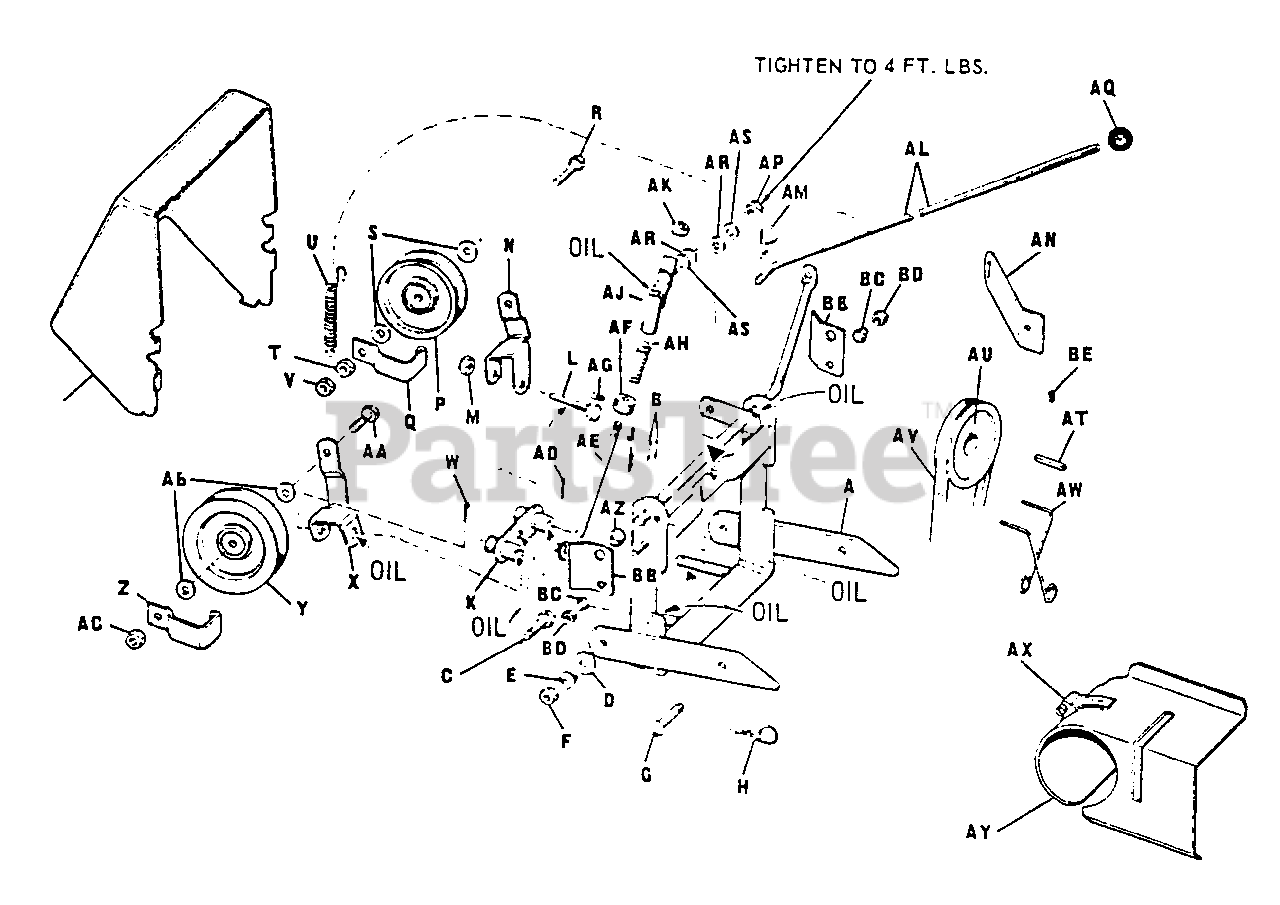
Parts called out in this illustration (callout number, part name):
A	Hitch Assembly
B	Cotter Pin, 1/8" Dia. x 1"
C	Hex. Cap Screw
D	Plain Washer, 3/8"
E	Spring Washer, 3/8"
F	Full Lock Hex. Nut, 3/8"-24
G	Pin
H	Spring Clip
J	Cotter Pin, 1/8" Dia. x 1"
K	Lever Ass'y Idler
L	Hex. Cap Screw
M	Full Lock Hex. Nut, 3/8"-16
N	Idler Bracket
P	Idler Pulley
Q	Guide Belt
R	Hex. Cap Screw. 3/8"-16 x 1-1/2 "
S	Plain Washer, 5/16"
T	Hex. Jam Nut
U	Return Spring
V	Full Lock Hex. Nut, 3/8"-16
W	Cotter Pin, 1/8" Dia. x 1"
X	Idler Bracket
Y	Idler Pulley
Z	Belt Guide
AA	Hex. Cap Screw, 3/8"-16 x 1-1/4"
AB	Plain Washer, 5/16"
AC	Full Lock Hex. Nut, 3/8"-16
AD	Cotter Pin, 3/32" Dia. x 3/4"
AE	Clutch Rod
AG	Set Screw, 1/4"-20 x 3/8"
AJ	Rod Assembly Guide
AK	Full Lock Hex. Nut, 5/16"-18
AL	Clutch Handle
AM	Spring Clip
AP	Stop Nut, 5/16"-18
AR	Nylon Washer
AS	Plain Washer, 5/16"
AU	Engine Pulley
AX	Deflector Clamp
AY	Heat Deflector
BA	Cover, Pulley
BB	Clip, Pulley Cover
BC	Spring, Concial
BD	Full Lock Hex. Nut, 5/16"-18
BE	Set Screw, 3/8" x 24 x 3/8"
